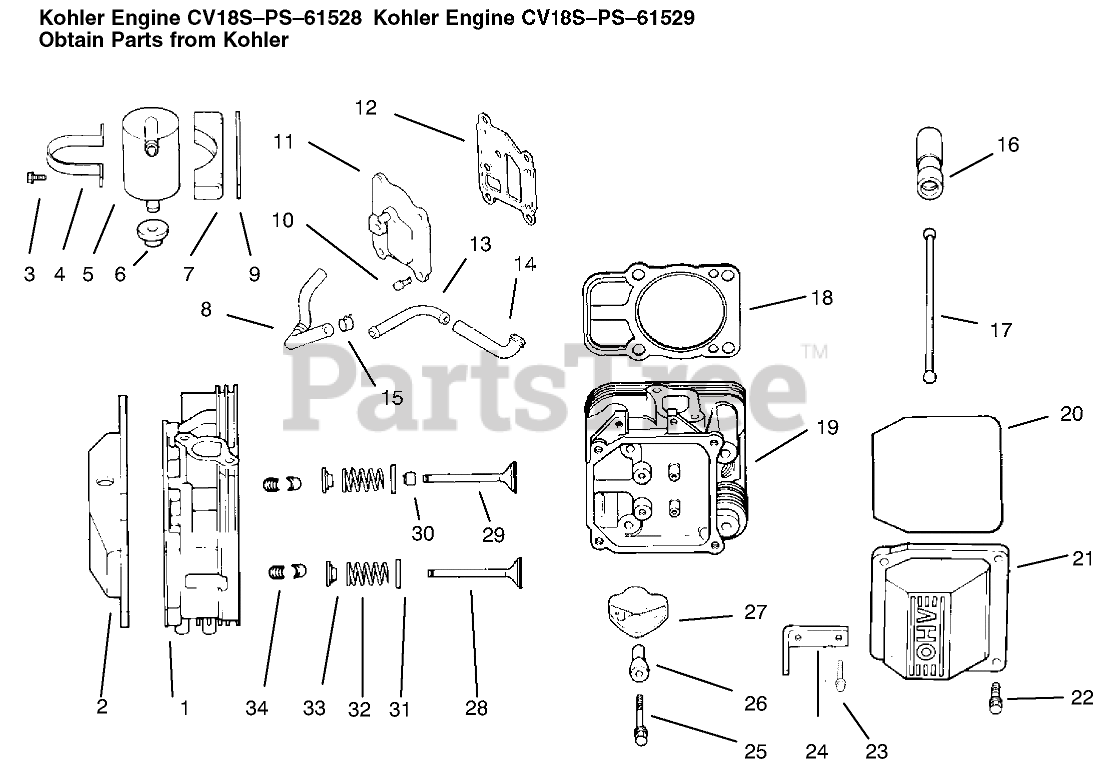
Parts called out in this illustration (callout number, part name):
1	#1 Cyl. Head Asm
2	Kit-Valve Incl 6 20-22
3	Screw-HF
4	Strap-Lifting
5	Kit-Breather Incl 3-9
6	Grommet-Rubber
7	Bracket
8	Hose-Breather
9	Spacer
10	Screw
11	Cover-Breather
12	Gasket-Breather
13	Fitting
14	Hose-Breather
15	Clamp
16	Lifter-Valve
17	Rod-Push
18	Gasket-Cylinder Head
19	#2 Cyl. Head Asm,
20	O Ring
21	Valve Kit
22	Screw
23	Screw
24	Strap-Lifting
26	Pivot-Arm, Rocker
27	Arm-Rocker
28	Valve-Exhaust
28	Valve-Exhaust (.25)
29	Valve-Intake
29	Valve-Intake (.25)
30	Seal-Stem, Valve
31	Retainer-Spring
32	Spring-Valve
33	Cap-Spring, Valve
34	Retainer Kit
